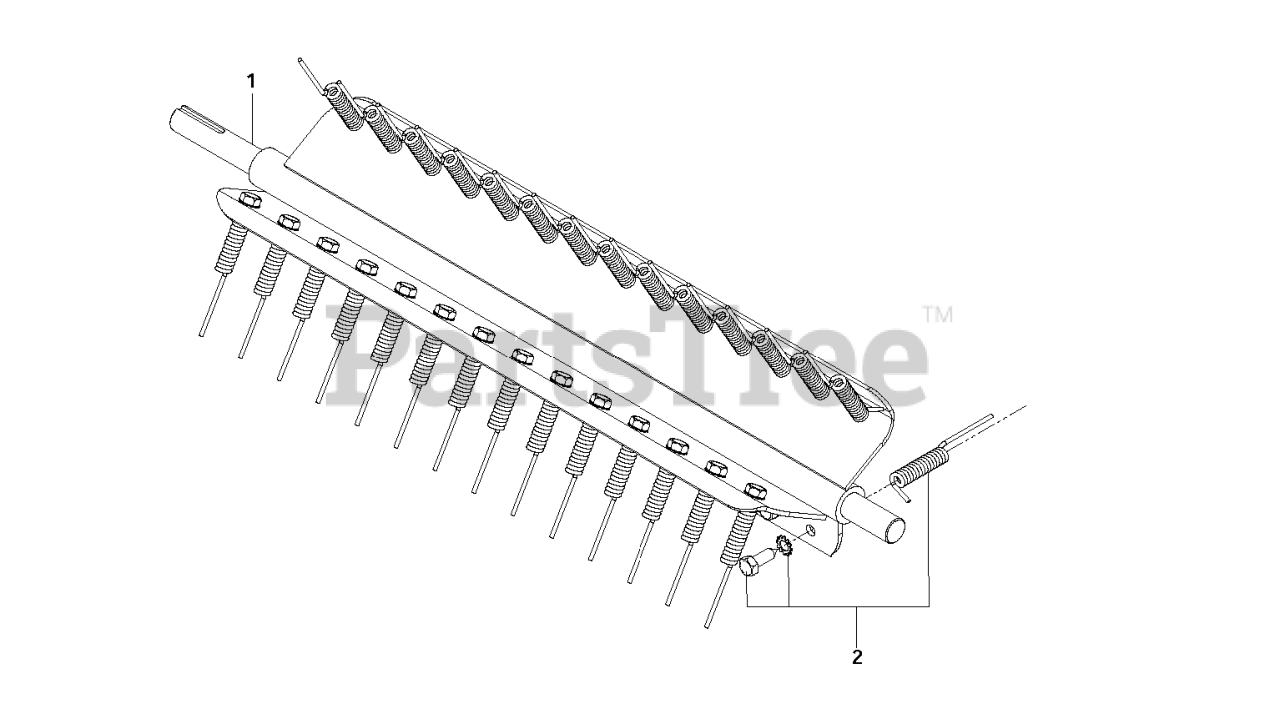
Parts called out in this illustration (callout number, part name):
1	22" SPRING REEL (COMPLETE)
1	SPRING TINE SHAFT
2	SPRING SET
